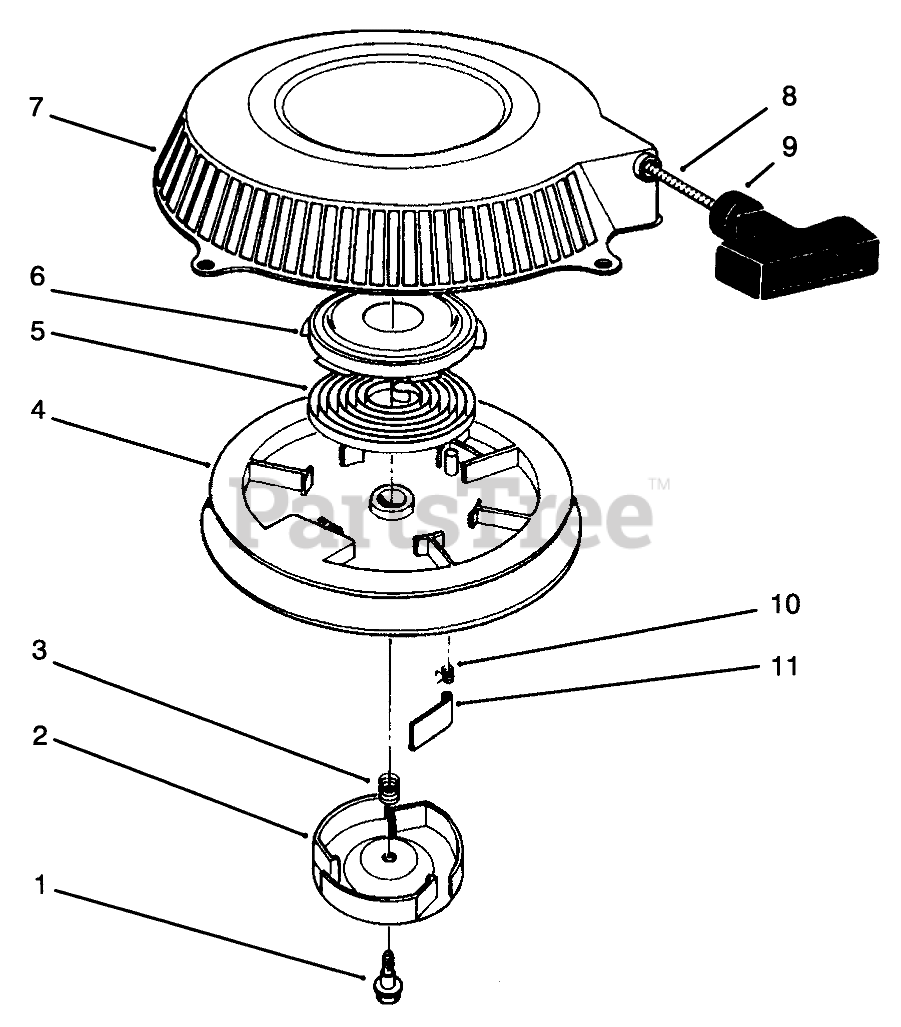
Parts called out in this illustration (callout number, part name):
1	Bolt
9	Grip
10	Spring-RETURN
11	Pawl
